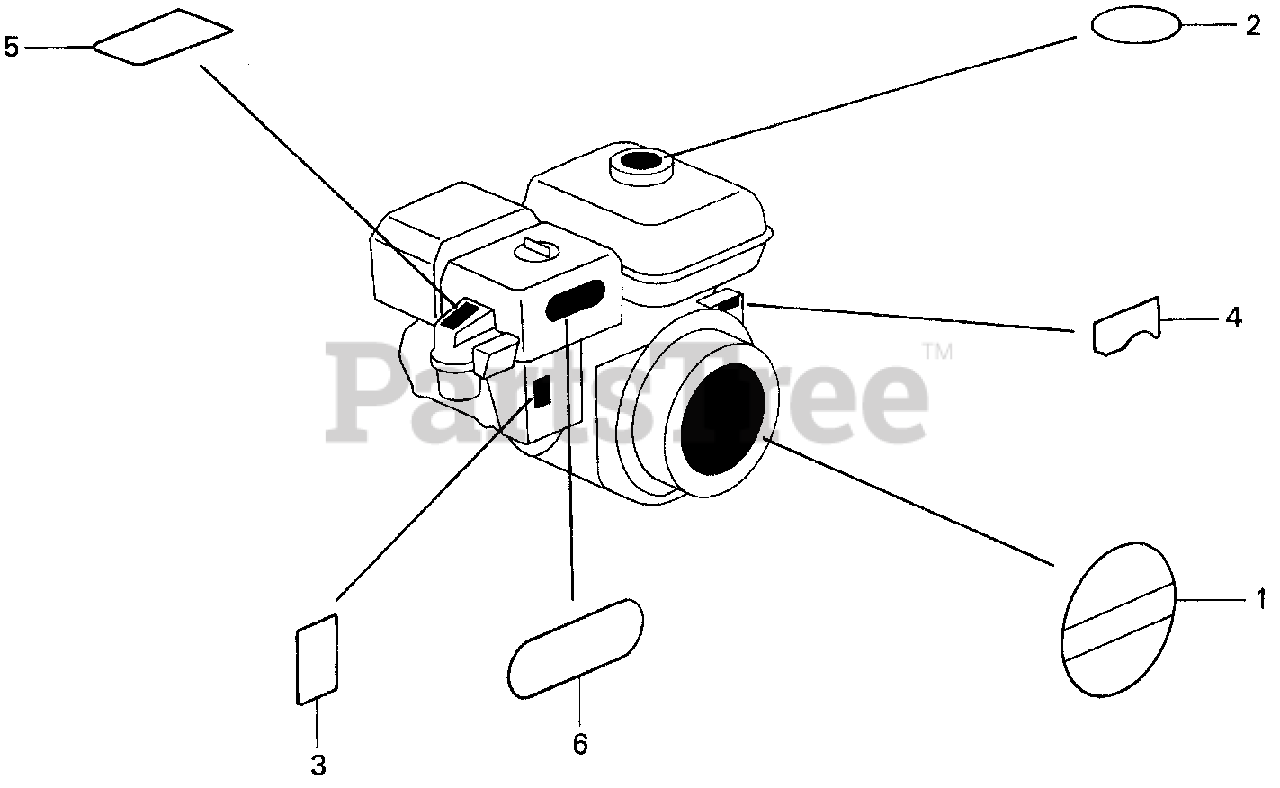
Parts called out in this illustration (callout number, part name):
1	EMBLEM (EXTERNAL)
2	MARK, CAUTION (EXTERNAL)
3	MARK, CHOKE
